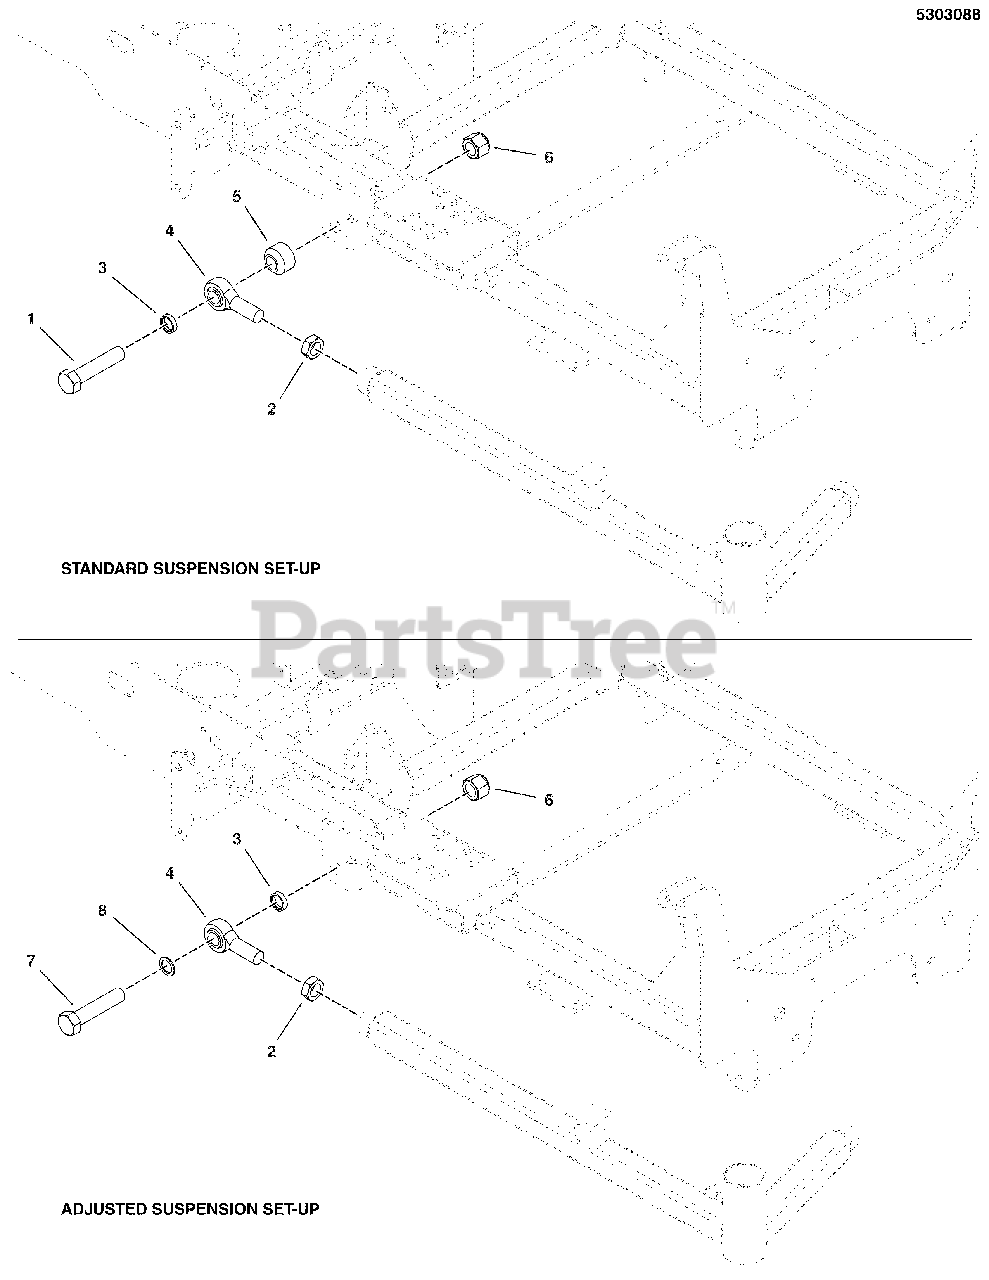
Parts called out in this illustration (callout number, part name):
1	BOLT, 3/4-16 X 3-1/2" YZ GD5
2	NUT, Hex, Jam, 3/4-16
3	SPACER, .76 x 1.00 x .25
4	BALL JOINT, 3/4-16, MALE
5	SPACER, .75 X 1.50 X 1.00, CZ
6	NUT, Hex, Nylon Lock, 3/4-16
7	HEX BOLT, MODIFIED, 3/4-16 X 2.5 GD5, CZ
8	WASHER-0.750(0.76IDX1.06ODX.07THK) BLK
